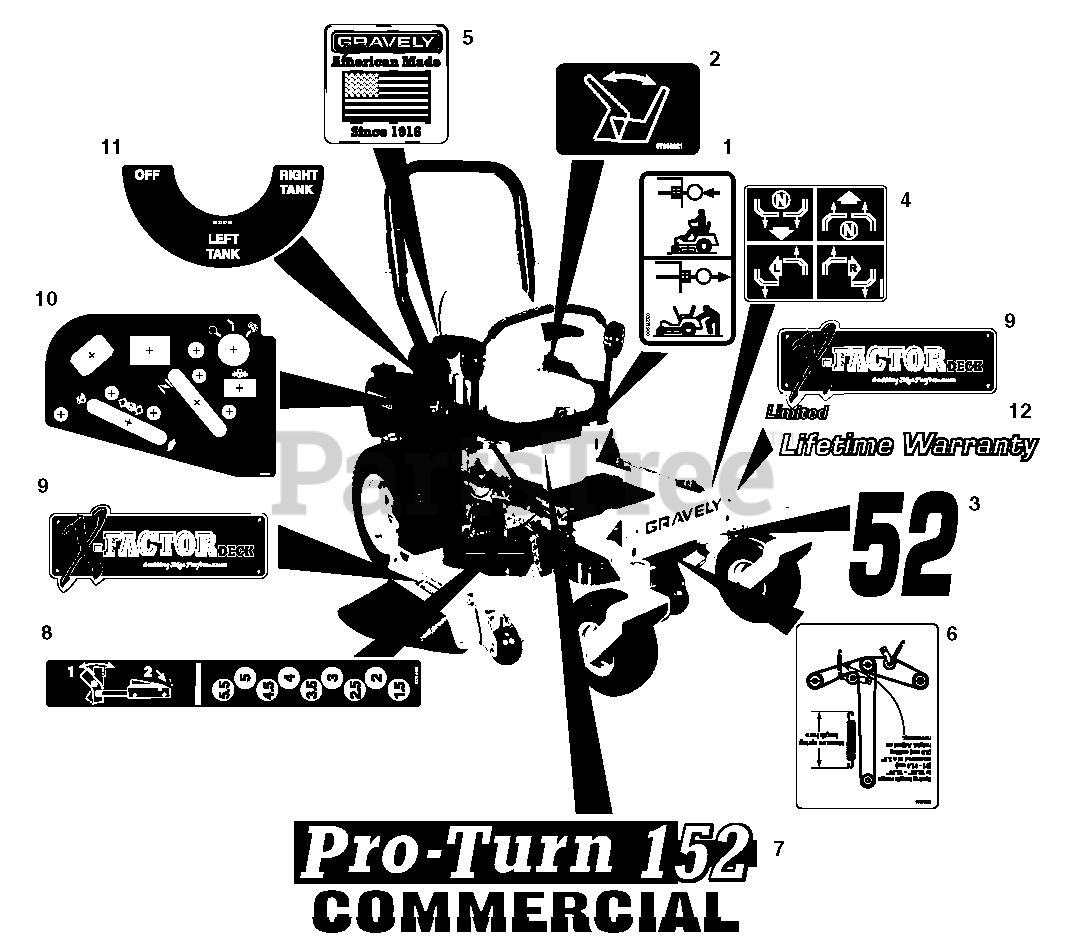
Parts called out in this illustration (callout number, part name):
1	Decal, Transmission Disconnect
2	Decal, Seat Release
3	Decal, 48 (076)
3	Decal, 52 (077)
3	Decal, 60 (078)
4	Decal, Instructional Steering
5	Decal, Gravely American Made
6	Decal, Belt Routing
7	Decal, Pro-Turn 148 (076)
7	Decal, Pro-Turn 152 (077)
7	Decal, Pro-Turn 160 (078)
8	Decal, Height of Cut
9	Decal, X-Factor Deck
10	Decal, Control Panel
11	Decal, Fuel Valve
12	Decal, Limited Lifetime Warranty
